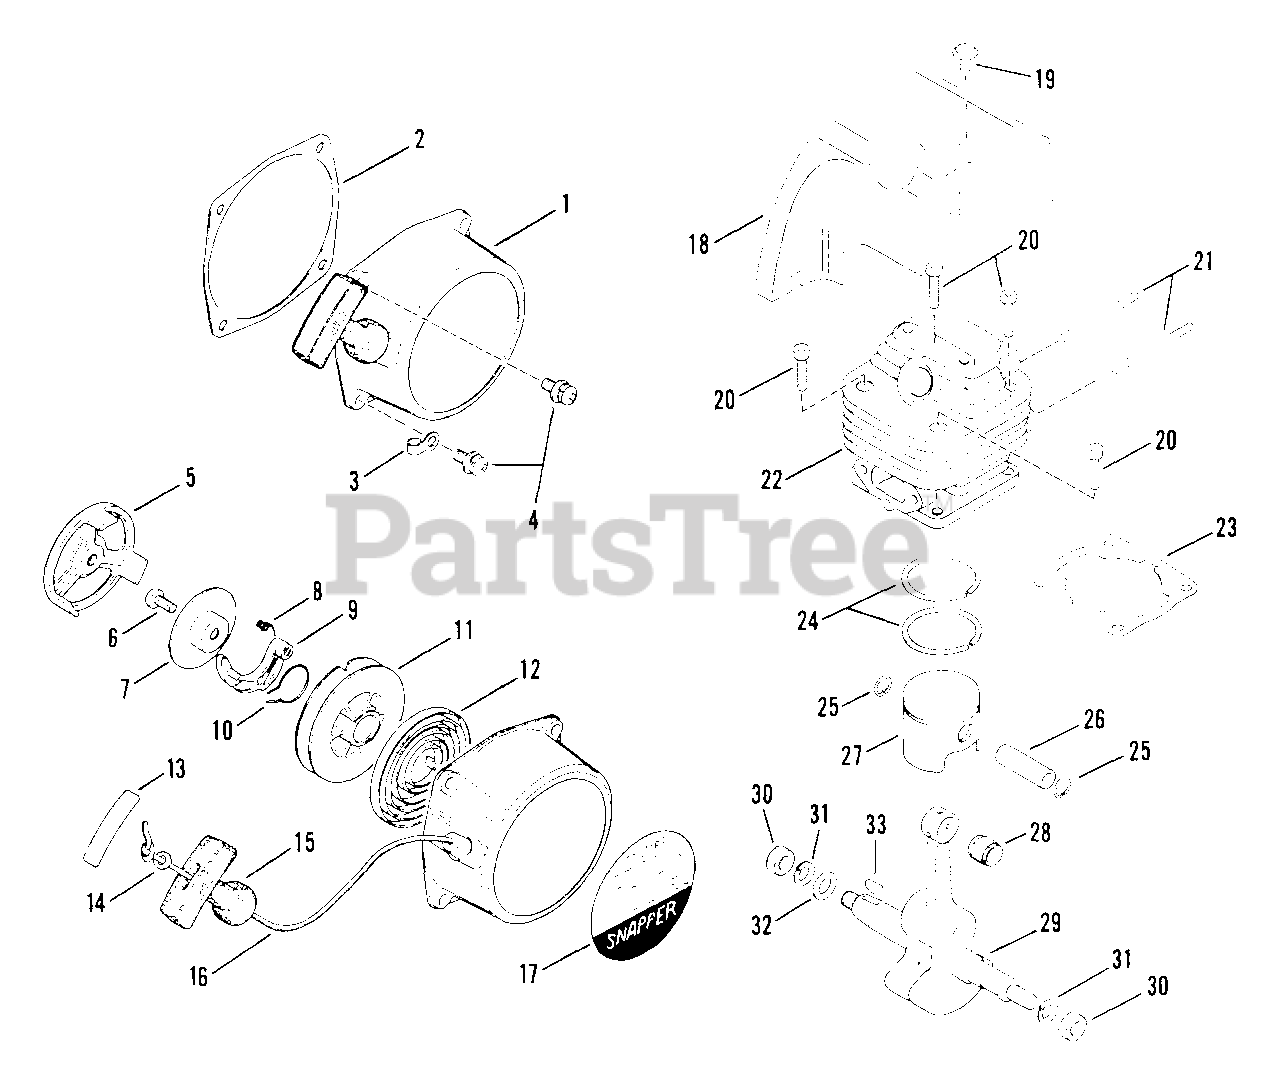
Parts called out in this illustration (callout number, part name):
1	RECOIL STARTER ASSM'Y.
2	GASKET, Recoil Starter
3	CLAMP, Fuel Tube
5	PULLEY, Recoil Starter
7	PLATE, Friction
8	SPRING, Return
9	RATCHET
10	SPRING, Friction
12	SPRING, Spiral
13	TAPE, Knob
15	KNOB, Recoil Starter
16	ROPE, Recoil Starter
17	DECAL, Starting
18	COVER, Cylinder
20	BOLT, Cylinder
21	STUD BOLT
22	CYLINDER
23	GASKET, Cylinder
24	RING, Piston
25	SNAP-RING, Piston Pin
26	PISTON
27	PIN, Piston
28	BEARING, Needle
29	CRANKSHAFT
30	NUT, Crankshaft
31	WASHER, Spring
